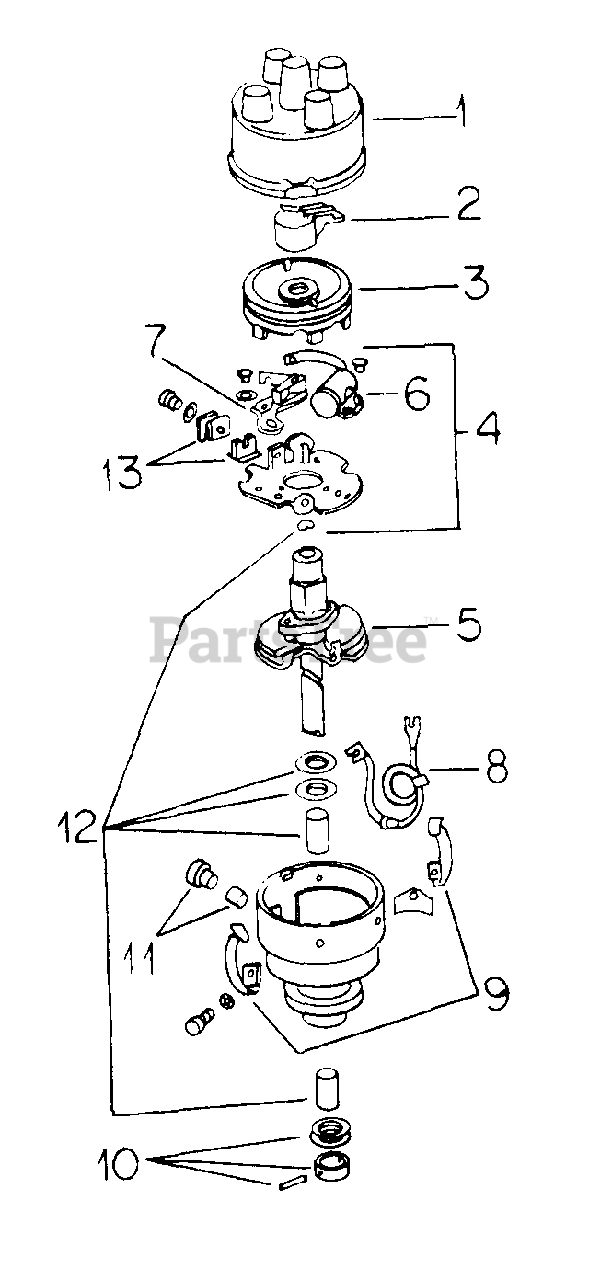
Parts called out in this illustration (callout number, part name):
1	CAP, DISTRIBUTOR
2	ROTOR, DISTRIBUTOR
3	COVER ASSY, DUST
4	PLATE ASSY, BREAKER
5	SHAFT ASSY, WEIGHT SPRING AND CAM
6	PACKAGE, CONDENSOR
7	PACKAGE, CONTACT BREAKER
8	LEAD ASSY, PRIMARY
9	PACKAGE, CAP CLAMP SPRING AND HINGE
10	PACKAGE, DRIVE GEAR
12	PACKAGE, SHAFT BEARING
13	PACKAGE, CLIP AND INSULATOR
